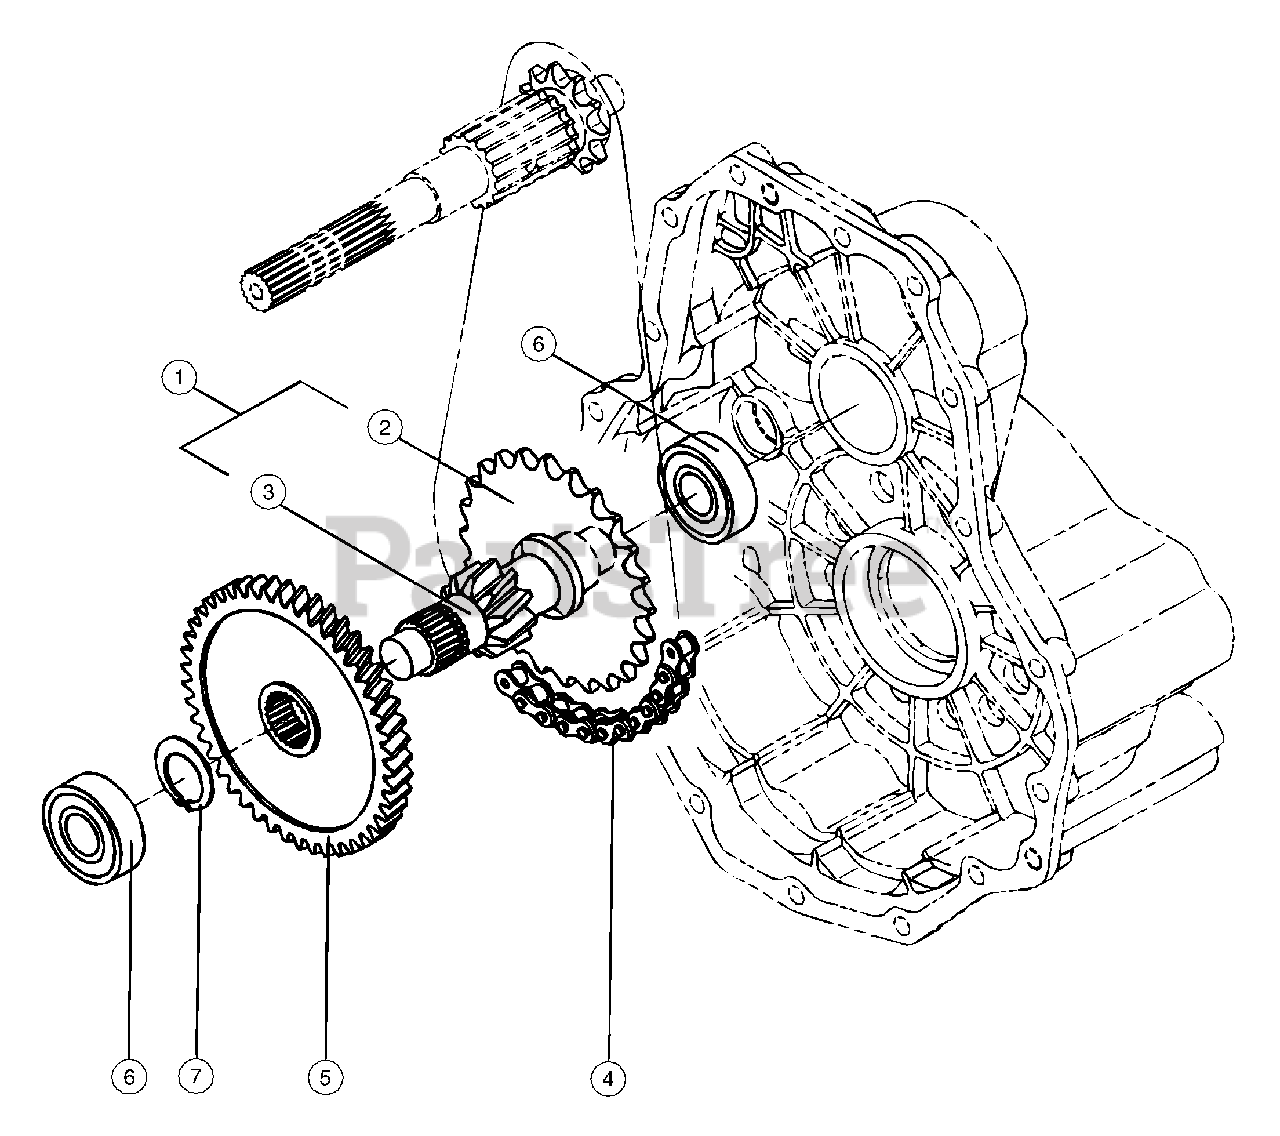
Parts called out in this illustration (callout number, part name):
1	Reduction Shaft Assembly
3	Shaft, Reduction
4	Chain, 40 x 34
5	Gear, 46H, Reduction
6	Bearing, 6204R, SH2
7	Ring, 26
